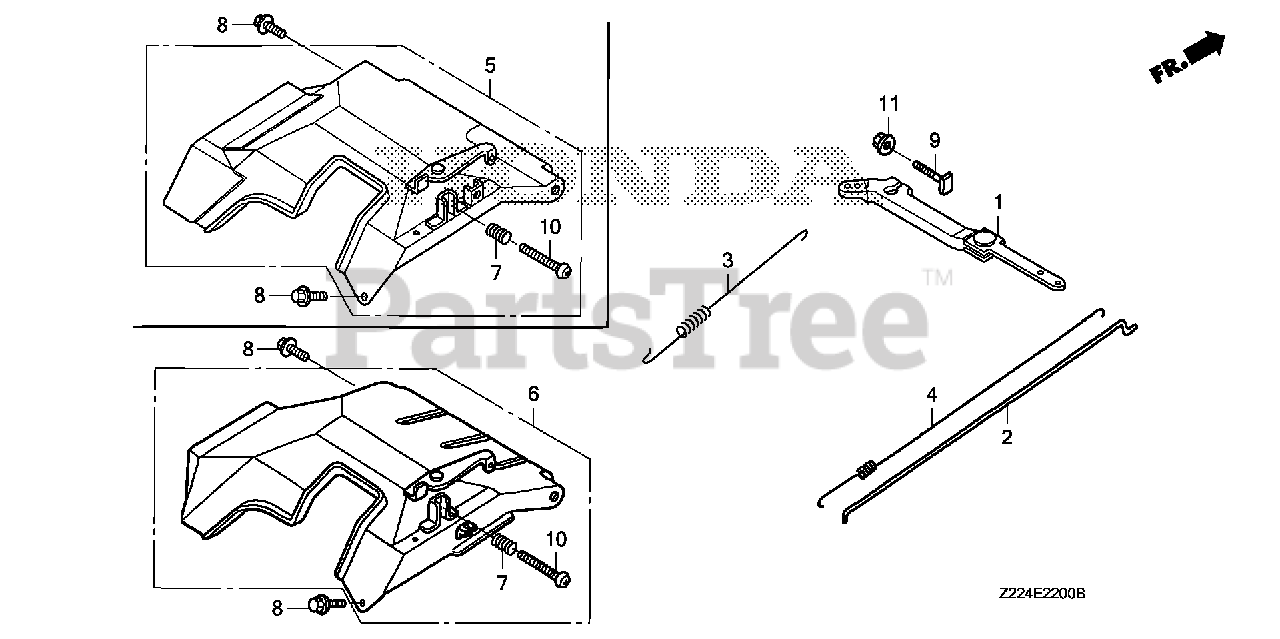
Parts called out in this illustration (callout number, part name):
1	ARM, GOVERNOR
2	ROD, GOVERNOR
3	SPRING, GOVERNOR
4	SPRING, THROTTLE RETURN
6	CONTROL ASSY.
7	SPRING, CONTROL ADJUSTING Use from Engine SN 2327377.
8	BOLT, FLANGE (6X12) (CT200)
9	BOLT, GOVERNOR ARM
10	SCREW, PAN (5X35)
11	NUT, FLANGE (6MM)
